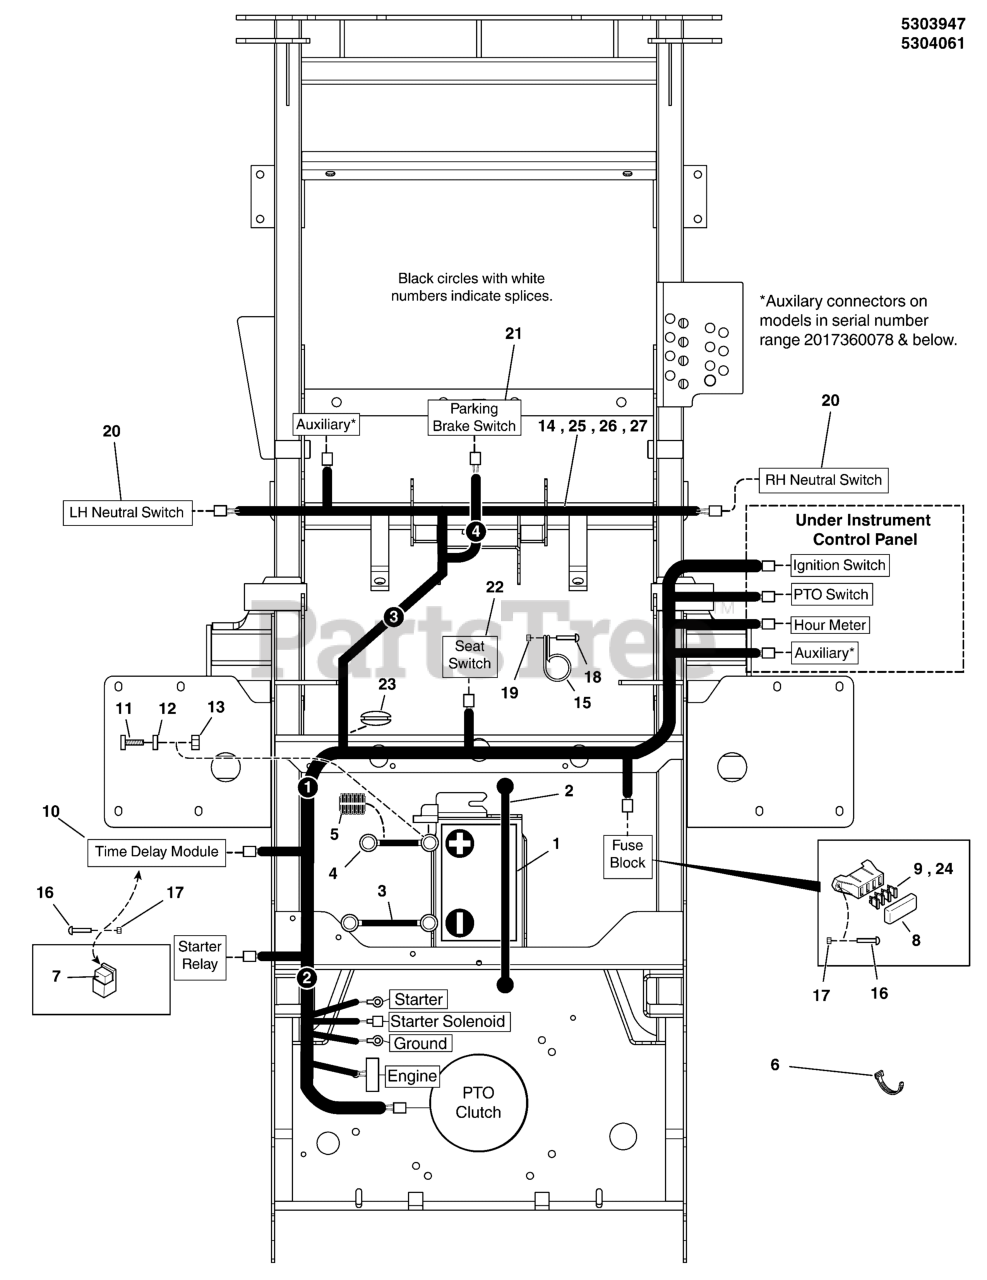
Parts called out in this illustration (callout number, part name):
1	BATTERY, WET ( BCIU1, 350 CCA)
2	STRAP-BLACK RUBB
3	BATTERY CABLE, NEG, 22, 1/4-5/16
4	BATTERY CABLE, POS, 22, 1/4-5/16
5	WIRE LOOM, 3/8 ID X 16 IN
6	TIE, SELF-LOCKING, 12"
7	RELAY, 12V, 40A
8	COVER, VINYL FUSEBLOCK
9	FUSE, ATO, 20 AMP
10	MODULE, TIME DELAY
11	BOLT, 1/4-20 X 3/4 GD5 CZ
12	WASHER, 1/4 SAE
13	NUT, 1/4-20 HEX NYLOCK FLANGE
14	WIRE HARNESS, BV32, IS2100/3100
15	CLAMP, VINYL INSULATED
16	SCREW, #10-24 X 3/4 ROUND PHILLIPS
17	NUT, #10-24 HEX NYLON LOCK
18	SCREW,1/4-20X1,ZINC PHOS & OIL
19	NUT, 1/4-20 HEX SERR. FLANGE
20	SWITCH, PLUNGER, NO, SINGLE POLE SNAP-IN
21	SWITCH, LOW PROF, NC/NO
22	SWITCH, PLUNGER, N.C.
23	GROMMET, 1-1/2" ID FOR 1/4" METAL
24	FUSE, ATO-15 (15 AMP)
25	WIRE HARNESS, KAWI FX, IS2100Z
26	WIRE HARNESS, BV32, IS2100/3200
27	WIRE HARNESS, KAWI FX, IS2100Z/IS3200
